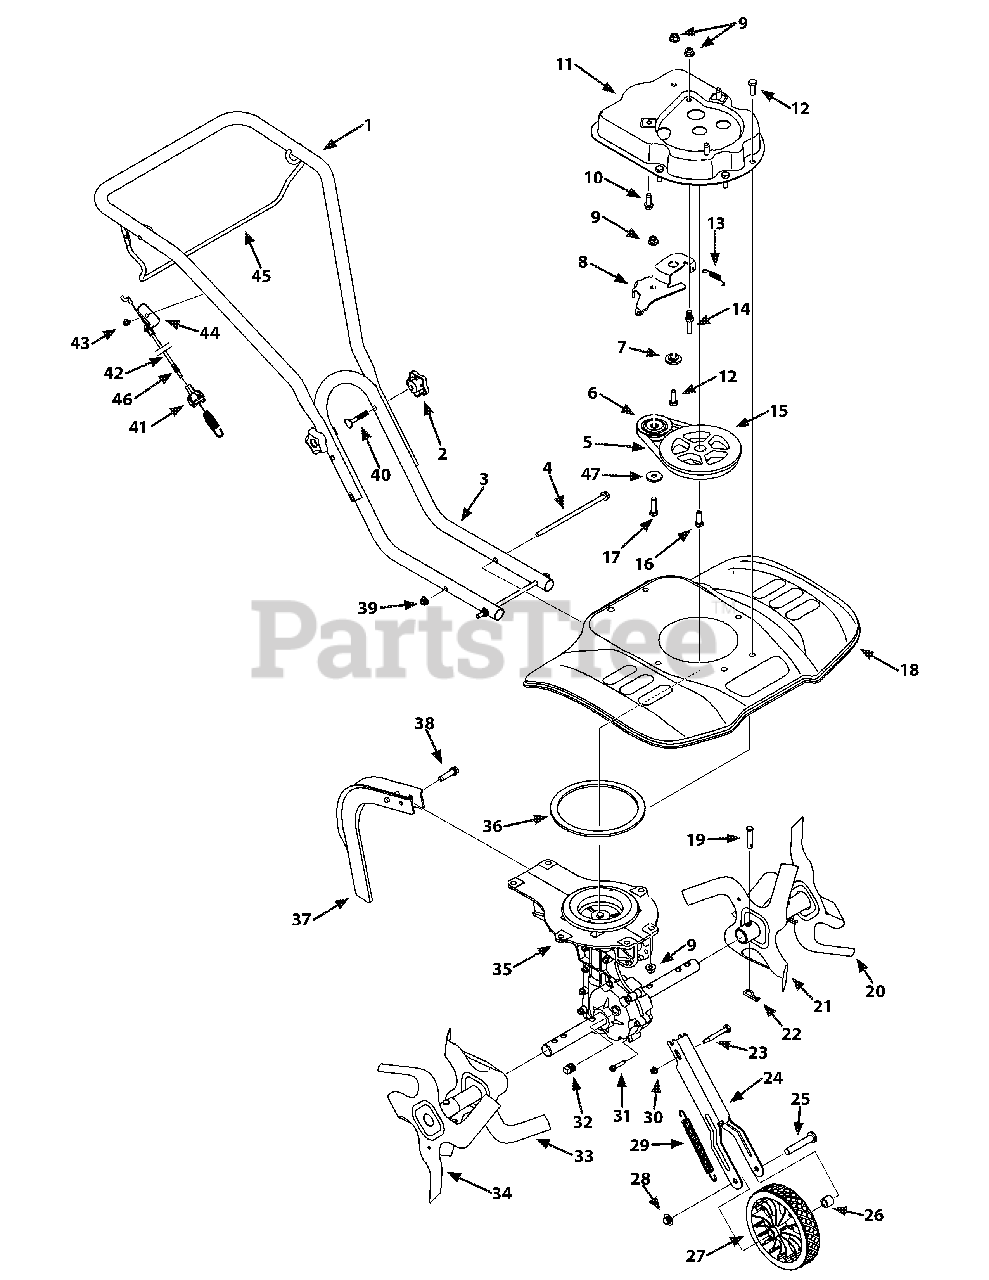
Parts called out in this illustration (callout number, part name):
2	Star Handle Knob
4	Flange Screw, 5/16-18:7.5 Gr 5
5	V-Belt
6	Idler Pulley
7	Shoulder Spacer
8	Idler Bracket
9	Flange Lock Nut, 3/8-16
10	TT Screw, 3/8-16 x 1.00
12	HH Cap Screw, 3/8-16:1.00
13	Extension Spring
14	Stud 33 x 1.5:3/8-16
15	Flywheel Pulley
16	HH Cap Screw, 3/8-24:1.00
17	HH Cap Screw, 3/8-16:1.55
19	Clevis Pin
22	Internal Cotter Pin
23	Shoulder Screw, 31 x 2:1/4-20
24	Front Wheel Axle Hardware Kit
25	Clevis Pin
26	Spacer
27	Wheel, 7 x 1.5 Star-Diam
28	Push Cap
29	Extension Spring
30	Flange Lock Nut, 1/4-20
31	TT Screw, 1/4-20:1.25
32	Pipe Plug, 3/8 NPT
35	Case Assembly
36	Gasket
38	TT Screw, 3/8-16:1.50
39	Flange Lock Nut, 5/16-18
40	Carriage Bolt
41	Clutch Cable Fitting
42	Clutch Cable
43	TT Screw, 1/4-20:.50
46	Retaining Ring
47	Flat Washer, .406 x .875 x .059
